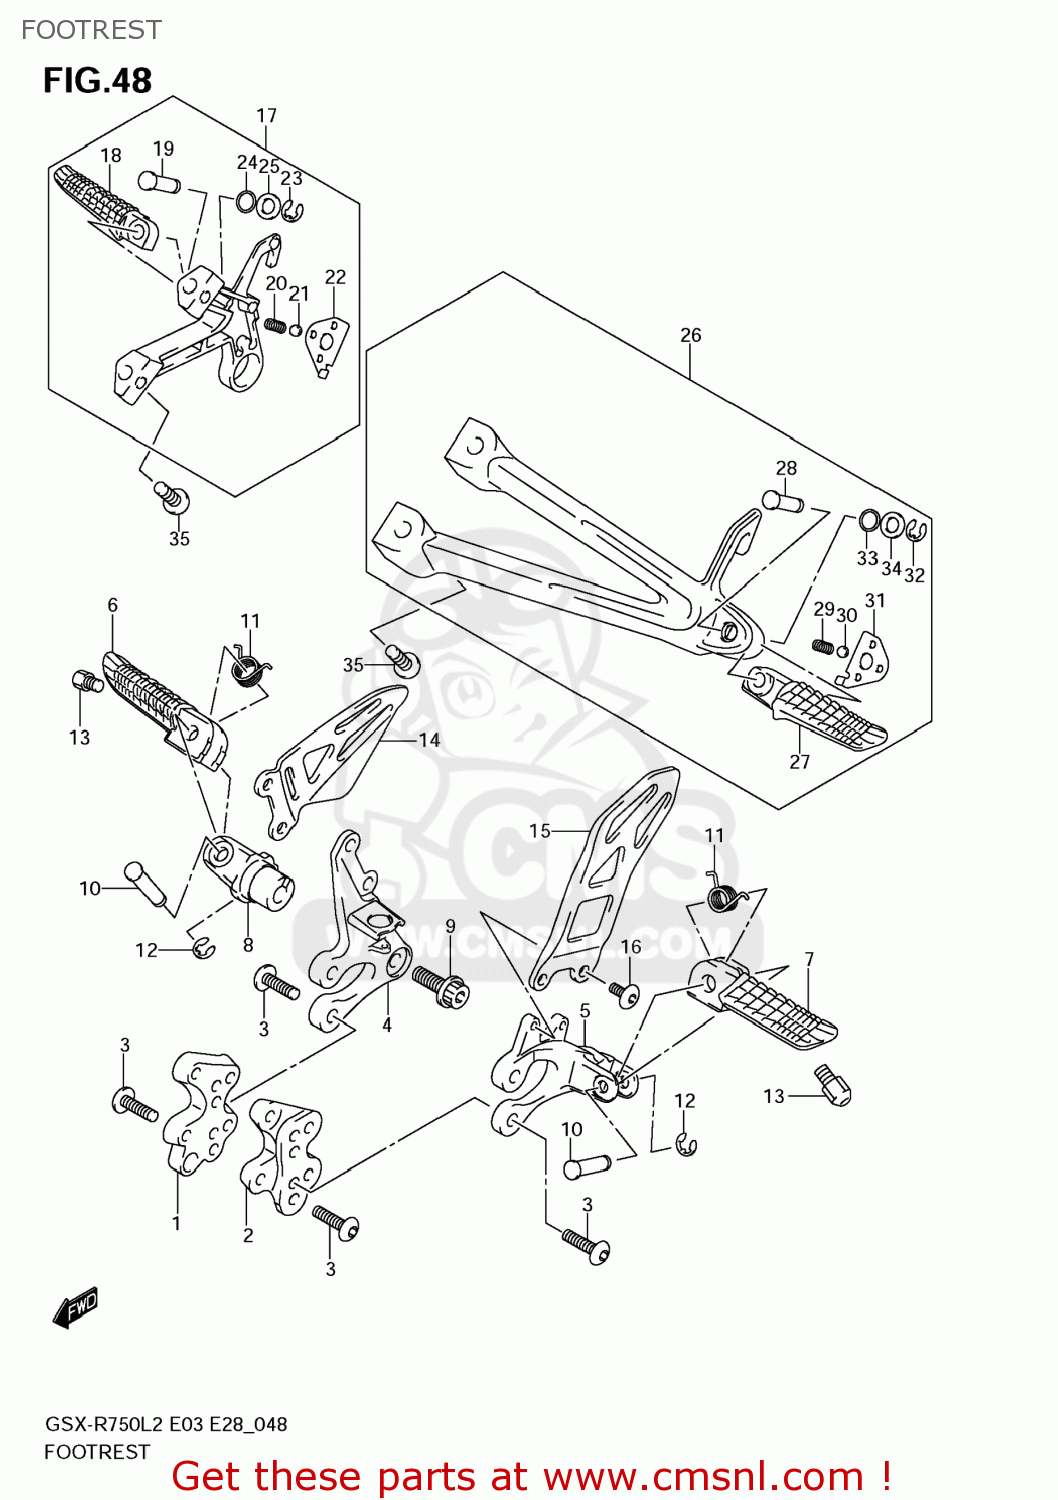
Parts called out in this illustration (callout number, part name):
1	BRACKET,FR FOOTREST NO.1,R
2	BRACKET,FR FOOTREST NO.1,L
3	BOLT(8X23)
4	BRACKET,FR FOOTREST NO.2,R
5	BRACKET,FR FOOTREST NO.2,L
6	BAR,FR FOOTREST,R
7	BAR,FR FOOTREST,L
8	HOLDER,FOOTREST
9	BOLT(10X28)
10	PIN
11	SPRING
12	E RING
13	BOLT,BANK SENSOR
14	GUARD,FR FOOTREST,R
15	GUARD,FR FOOTREST,L
16	SCREW,FOOTREST GUARD,L
17	FOOTREST ASSY,PILLION,R
18	BAR,PILLION FOOTREST,R
19	PIN
20	SPRING
21	BALL
22	PLATE,PILLION FOOTREST,R
23	E RING
24	O RING(D:2.4,ID:6.9)
25	WASHER(8.5X14X1.0)
26	FOOTREST ASSY,PILLION,L
27	BAR,PILLION FOOTREST,L
28	PIN
29	SPRING
30	BALL
31	PLATE,PILLION FOOTREST,L
32	E RING
33	O RING(D:2.4,ID:6.9)
34	WASHER(8.5X14X1.0)
35	BOLT(8X23)
